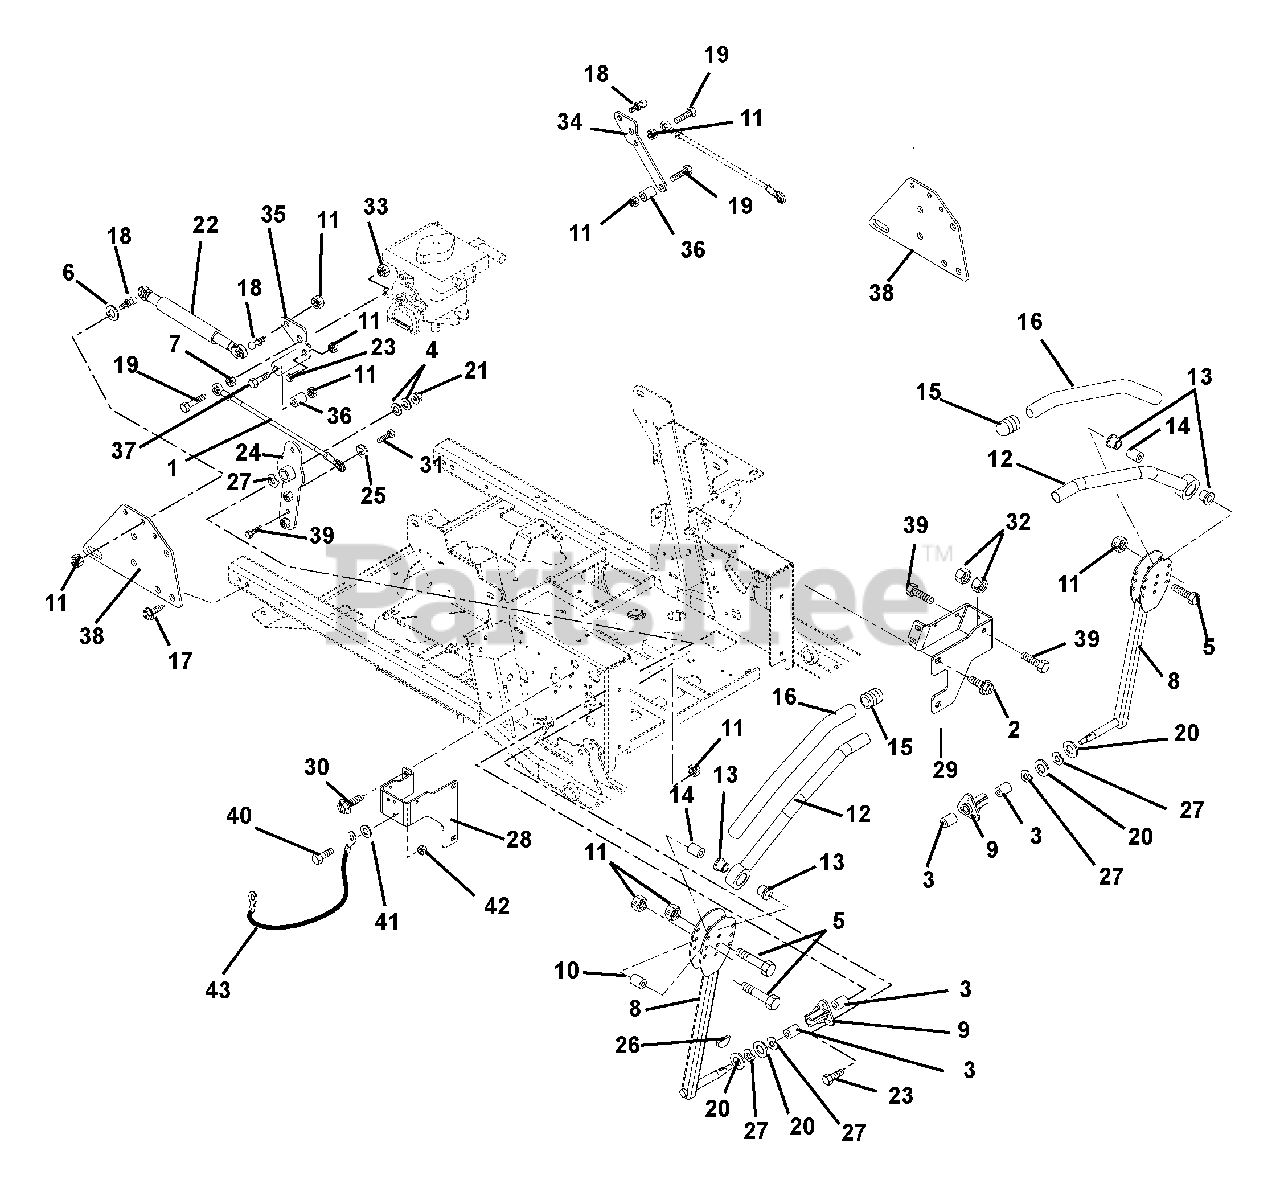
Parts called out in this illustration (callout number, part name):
1	Assembly, Steering Rod .38 Rod x 7.60
2	Screw, Tapping .38-16 x .75 Hex Washer Head
3	Bushing .625 x .75 x .50
4	Washer, Flat Steel .403 x .812 x .065
5	Bolt, Hex .31-18 x 1.75 Grade 5
6	Washer, Flat Steel .344 x .688 x .065
7	Nut, Hex .38-16
8	Control Arm
9	Bushing, Flange
10	Eccentric
11	Nut, Locking Top Flange .31-18
12	Handle Weldment Left-Hand
12	Handle Weldment Right-Hand
13	Bushing, Flange Nylon .762 x 1.48 x .44
15	Caplug, Handlebar
16	Grip, Handlebar
17	Screw, Tapping .31-18 x .50 Hex Washer Head
18	Stud, Ball
19	Bolt, Hex .38-16 x 1.50 Grade 5
20	Washer, Flat Steel .63 x 1.005 x .062
21	Nut, Locking Top Flange .38-16
22	Damper, Control
23	Bolt, Hex .31-18 x .75 Grade 5
24	Weldment, Pivot Arm
25	Washer, Locking .38 x .094 Regular
26	Key, Woodruff .13 x .63
27	Washer, Wave
28	Stop, Steering Right Hand
29	Stop, Steering Left Hand
30	Screw, Tapping .38-16 x .50 Hex Washer Head
31	Bolt, Hex .38-16 x 1.25 Grade 5
32	Nut, Hex Jam .375-16
33	Nut, Locking Center .38-16
34	Bracket, Left Hand
35	Bracket, Right Hand
36	Spacer .318 x .43 x .375
37	Bolt, Hex .31-18 x 1.25 Grade 5
38	Bracket, Damper
39	Bolt-Hex .375-16 x 1.75 Full Thread
40	Bolt-Hex .25-20 x .75 Grade 5
41	Washer, Flat Steel .265 x .50 x .087
42	Nut, Locking Top Flange .25-20
43	Cable, Hood
